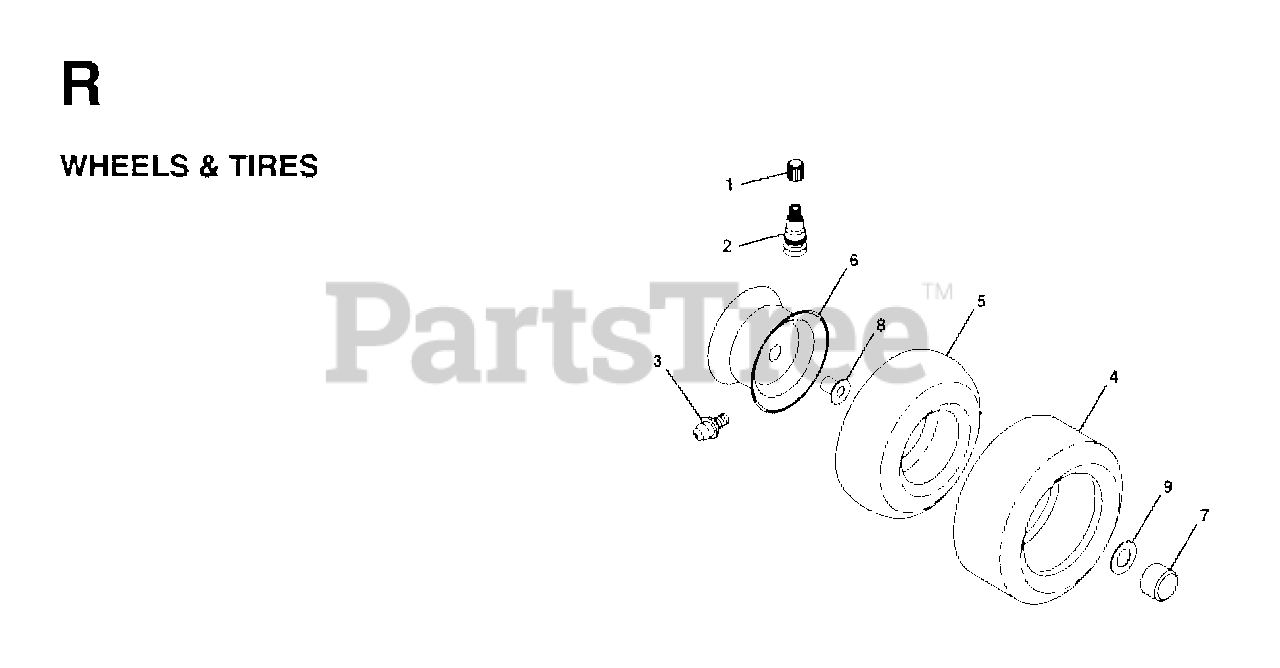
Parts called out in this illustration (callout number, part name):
1	VALVE CAP
2	VALVE STEM LT
3	FITTING LT
4	TIRE FRONT 15X6-6
4	REAR TIRE
5	TUBE.5.3/4.5/6
5	TUBE.16X6.5/7.5-8
6	RIM
6	RIM REAR 8"
7	CAP-HUB FRONT LT
8	BEARING T
